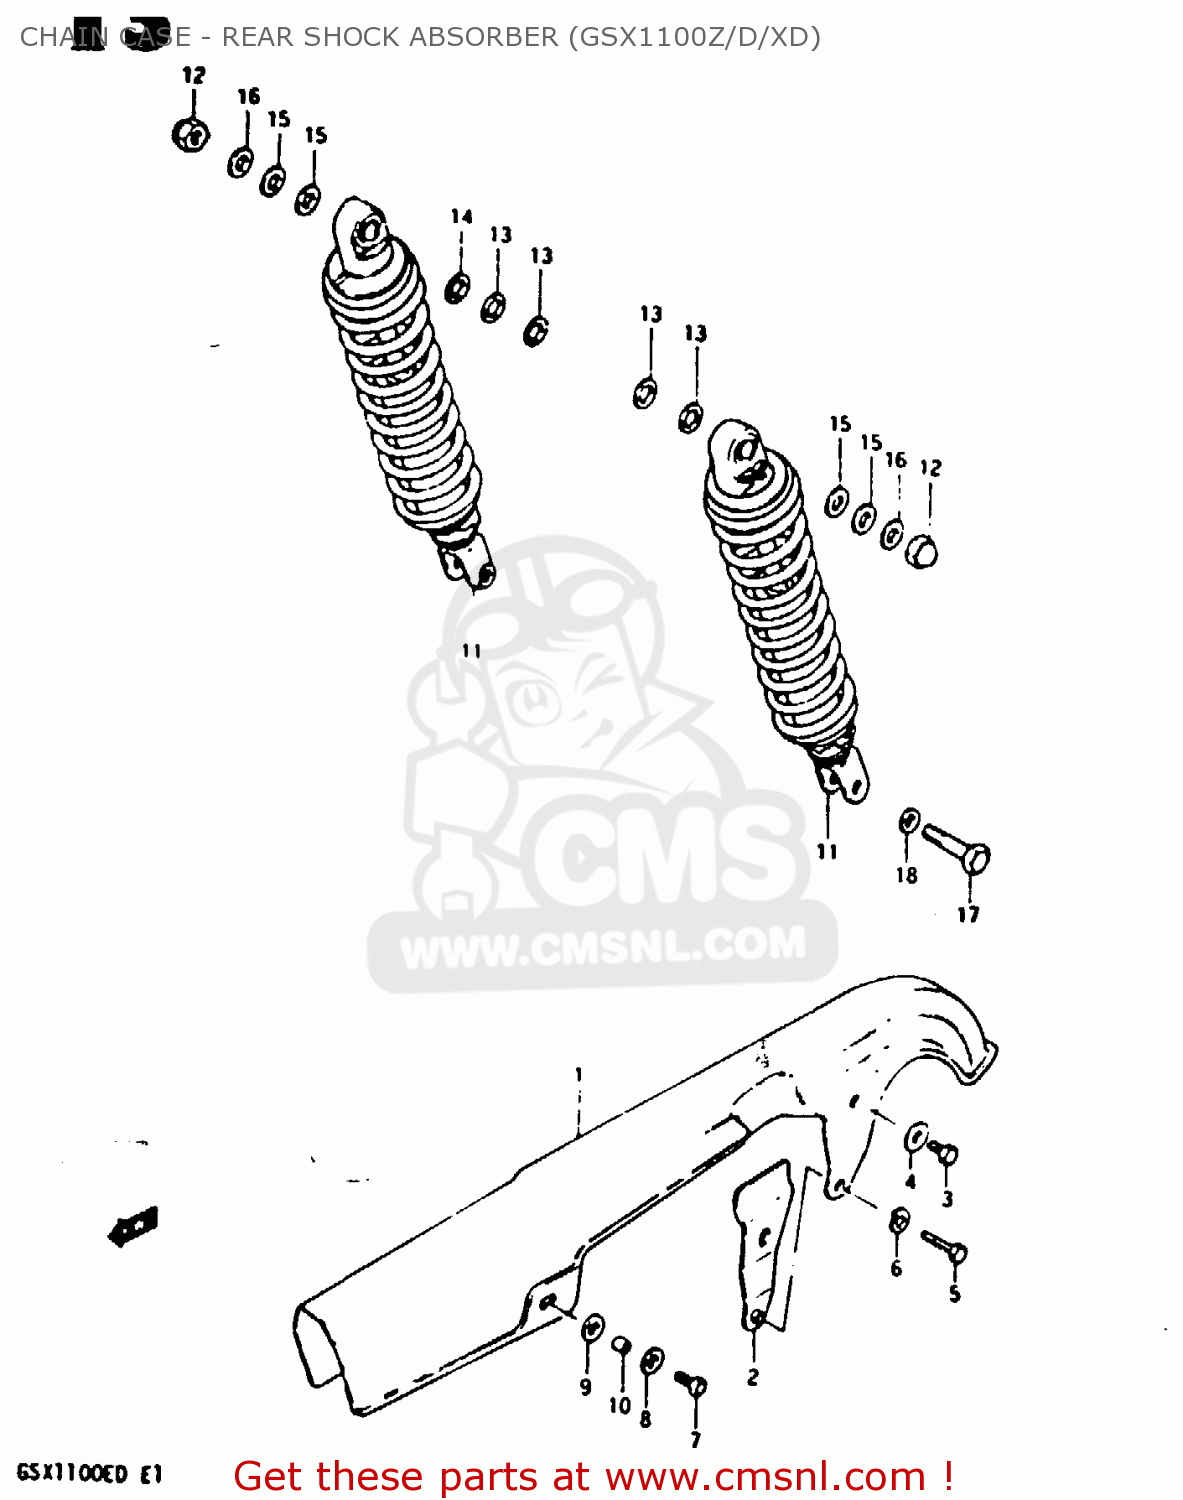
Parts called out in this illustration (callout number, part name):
1	CASE,CHAIN
2	REINFORCEMENT,CHAIN CASE
3	BOLT(6X8)
4	WASHER
5	BOLT
6	LOCK WASHER
7	BOLT
8	WASHER(6.5X18X1)
9	CUSHION
10	SPACER (6.1X8X5.2)
11	SHOCK ABSORBER, REAR
12	NUT, LOWER LH
13	WASHER
14	WASHER (12.5X24X3.2)
15	WASHER
16	WASHER(10.5X24X3.2)
17	BOLT(10X36)
18	WASHER
